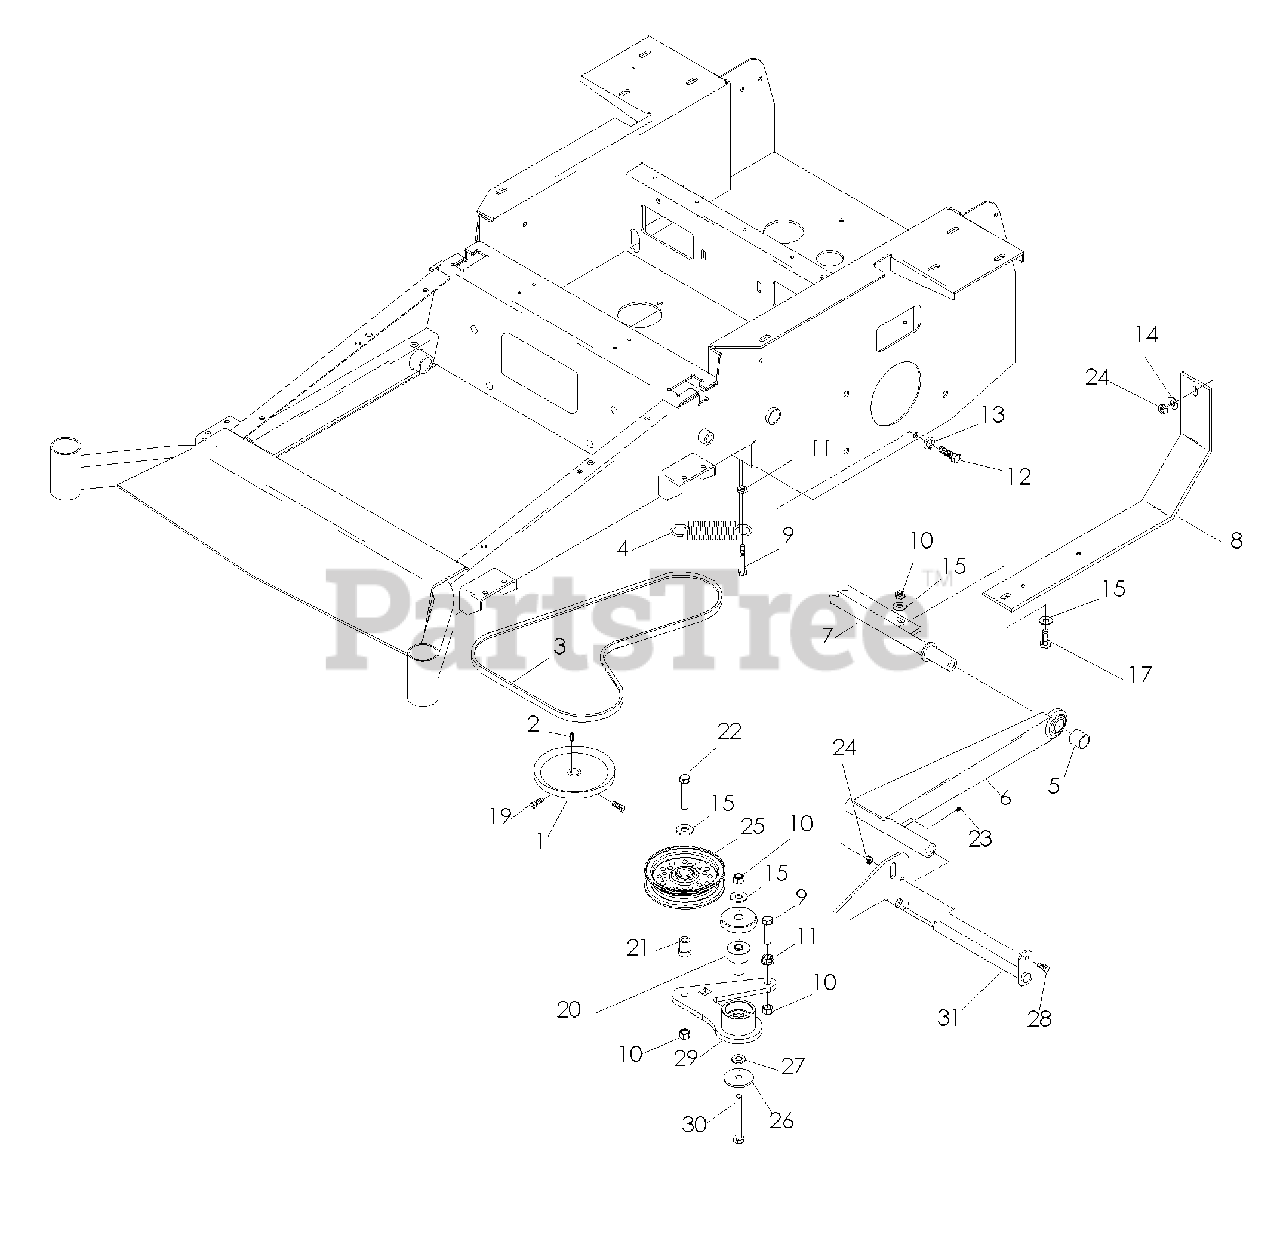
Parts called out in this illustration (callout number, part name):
3	BELT, PUMP
5	STRUT SPACER
6	STRUT WELDMENT, REAR
7	CROSS SHAFT
8	SKID PLATE
9	HCS 3/8-16 x 1 1/2
10	NUT 3/8-16 HEX NYLOC
11	NUT 3/8-16 HEX WHIZLK
12	BOLT, BLADE W/WASHER
13	LOCKWASHER 7/16
14	WASHER 5/16 STD FLT
15	WASHER 3/8 STD FLT
16	HCS 1/2-13 x 3 1/4
17	HCS 3/8-16 x 1
18	NUT 1/2-13 HEX NYLOC
19	SCREW, SET
20	PIVOT, BEARING
21	IDLER FLANGE BUSHING
22	HCS 3/8-16 x 2
23	ZERK
24	NUT 5/16-18 HEX NYLOC
25	PULLEY, IDLER
26	WASHER 3/8 SPEC
27	WASHER 3/8 SAE FLT
28	HCS 5/16-18 x 1
29	ARM, IDLER
30	HCS 3/8-16 x 3
31	PIVOT PIN WELDMENT
